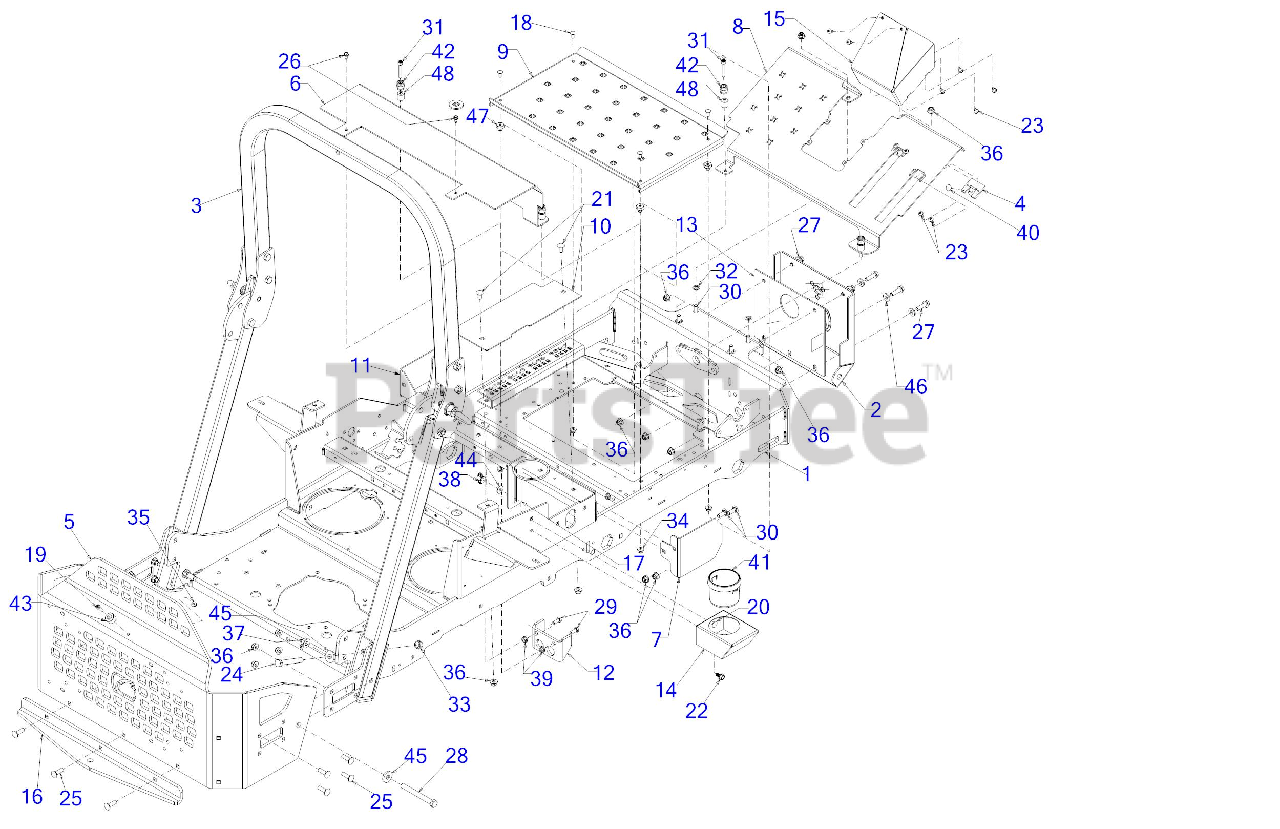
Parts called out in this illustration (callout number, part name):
3	COMPLETE ROPS ASSEMBLY
18	CARRIAGE BOLT 1/4-20 x .62
19	MACHINE SCREW 1/4-20:1
20	CARRIAGE BOLT 5/16-18 x 1.00
21	CARRIAGE BOLT 3/8-16 x .750 GR5
22	SCREW 5/16-18 x .750
23	SCREW 1/4-20 x .5
24	SCREW 1/2-20 x 3.50 GR5
25	CARRIAGE BOLT 3/8-16 X1.25 GR5
26	SCREW 1/4-20 X.500
27	SCREW 3/8-16 x 1.25 GR5
28	SCREW 1/2-13 x 4.5 GR 5
29	SCREW 5/16-18 x .75 GR5
30	CARRIAGE BOLT 3/8-16 x 1.00 GR5
31	SCREW 5/16-18X1.75 GR5
33	HEX NUT
34	FLANGE LOCK NUT 5/16-18
35	FLANGE LOCK NUT
38	WING NUT 5/16-18
39	FLANGE NUT
40	RATCHET CLIP
42	RADIAL BUMPER
44	FLAT WASHER
45	FLAT WASHER .531 x 1.25 x .181
46	FLAT WASHER
47	SHOULDER SPACER
